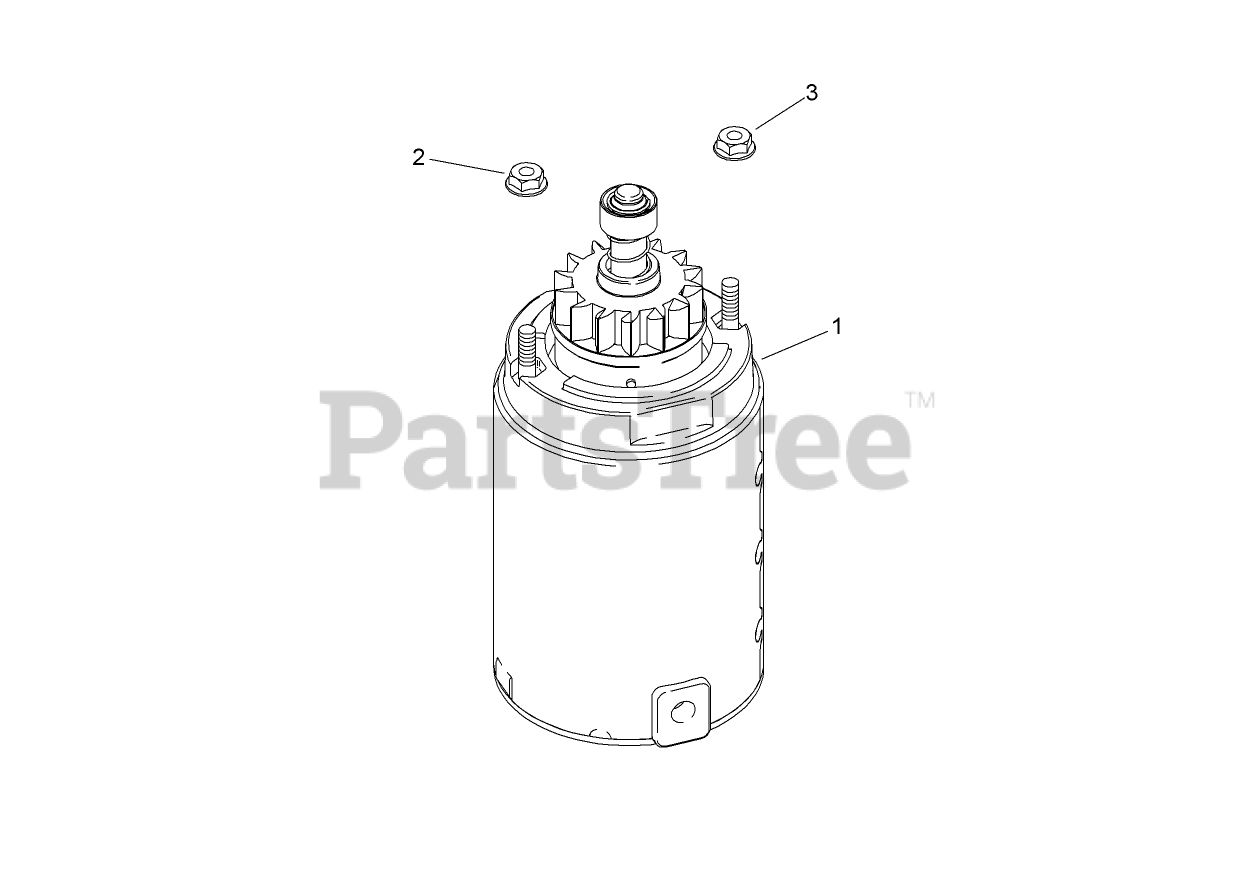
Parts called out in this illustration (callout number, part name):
1	STARTER ASM (SERVICE WITH REF 3-6)
2	Nut-Flange, Hex Serrated (10-24)
3	Nut-Flange, Hex (1/4-20)
